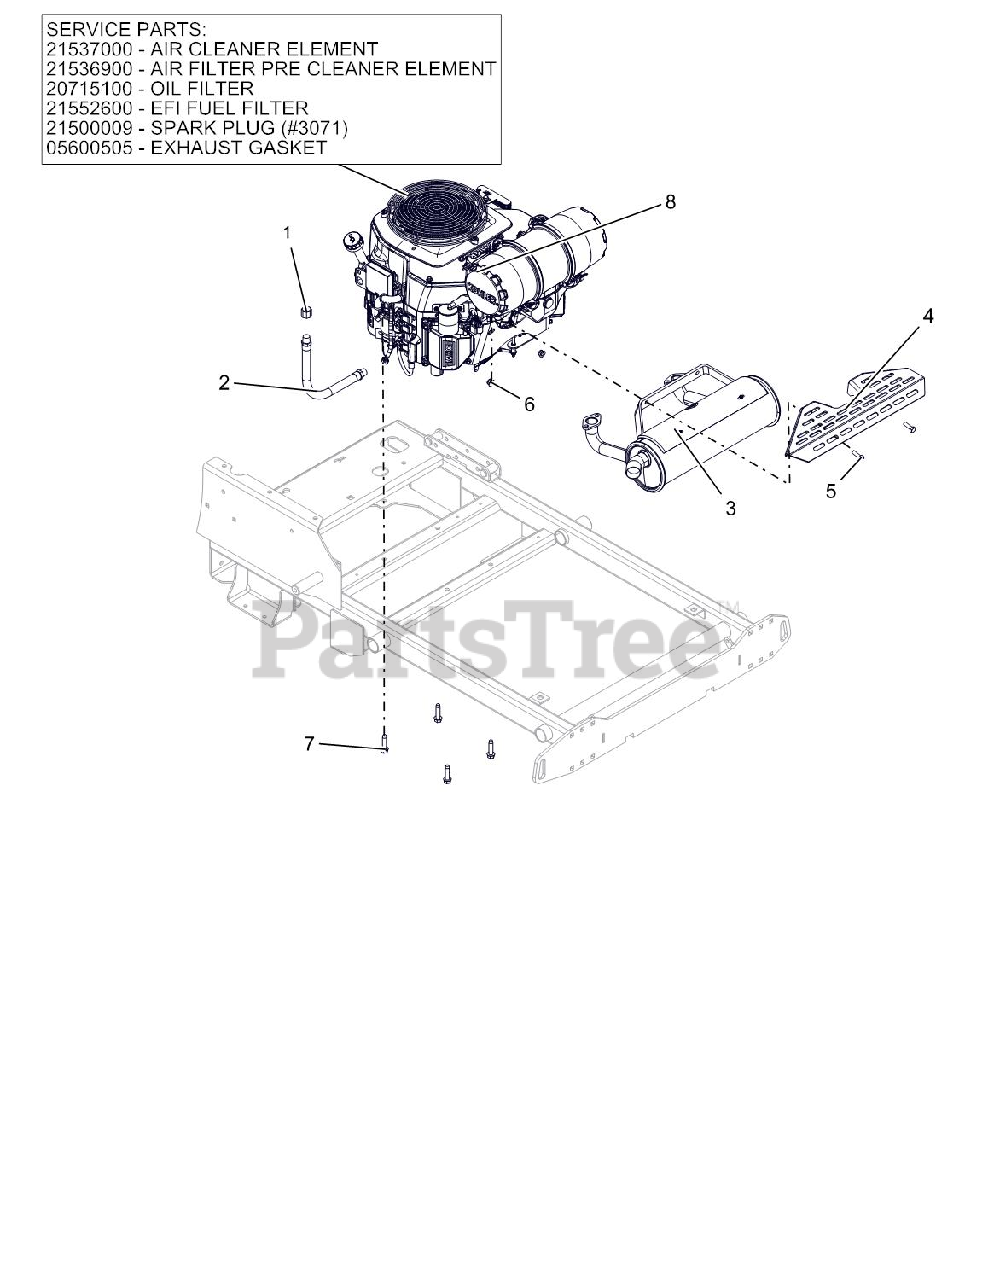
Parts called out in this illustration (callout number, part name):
1	PIPE CAP 3/8 NPT FEMALE
2	HOSE,HYD .38-14-0K M6N0-M6N0
3	MUFFLER, KOHLER EFI PRO-STANCE
4	GUARD, MUFFLER
5	@BLT-HEX .31-18X1.00 GR5 YWZC
6	@NUT-LK-NYL-FLG .31-18 YWZC
7	@SCR-TAP .38-16X1.50 HWH TR YZ
8	ELEMENT, INNER SAFETY
8	ELEMENT, OUTER PRIMARY
8	GASKET, MUFFLER KOHLER TWIN
8	ENGINE, KOHLER PCV740 EFI LP
8	PLUG, SPARK KOHLER
8	OIL FILTER KOHLER
8	FILTER-FUEL KOHLER PROPANE
